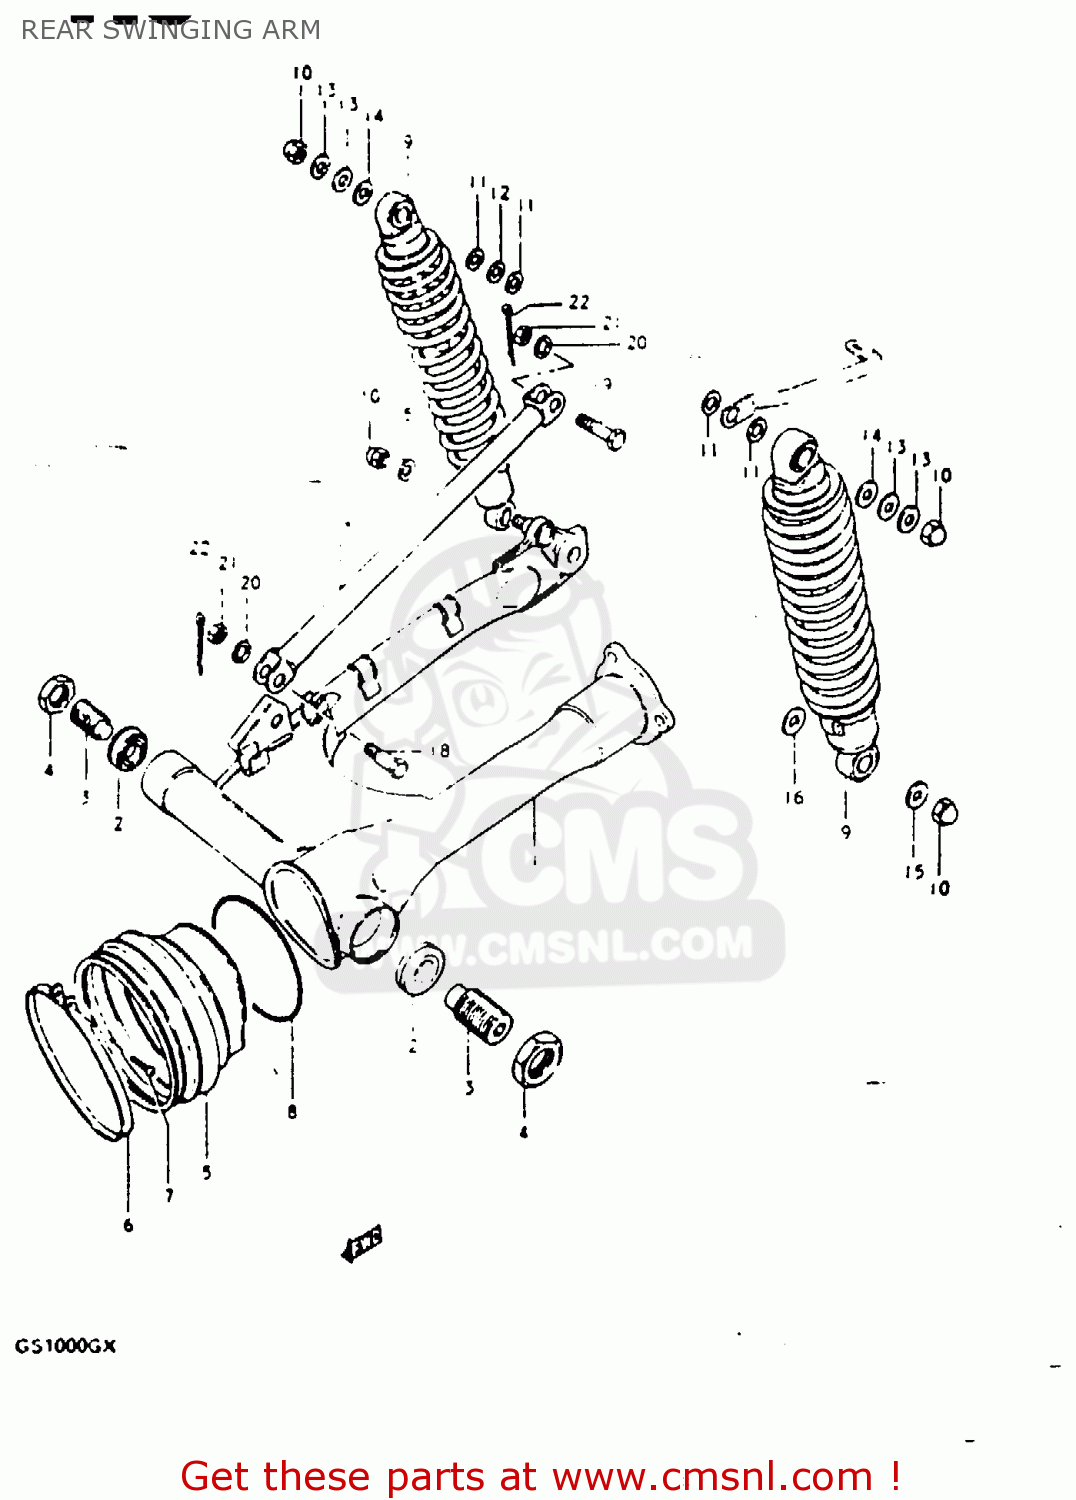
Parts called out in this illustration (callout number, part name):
1	SWING ARM ASSEMBLY,REAR
2	BEARING(17X40X13.25)
3	BOLT,REAR SWING ARM PIVOT
4	NUT
5	BOOT,PROPELLER SHAFT
6	CLAMP
7	SCREW 4X25
8	SPRING,PROPELLER SHAFT
9	SHOCK ABSORBER, REAR
10	NUT, LOWER LH
11	WASHER
12	WASHER (12.5X24X3.2)
13	WASHER
14	WASHER(10.5X24X3.2)
15	WASHER
16	WASHER
17	LINK,REAR TORQUE
18	BOLT
19	BOLT(10X39)
20	WASHER
21	NUT
22	PIN 20X20
